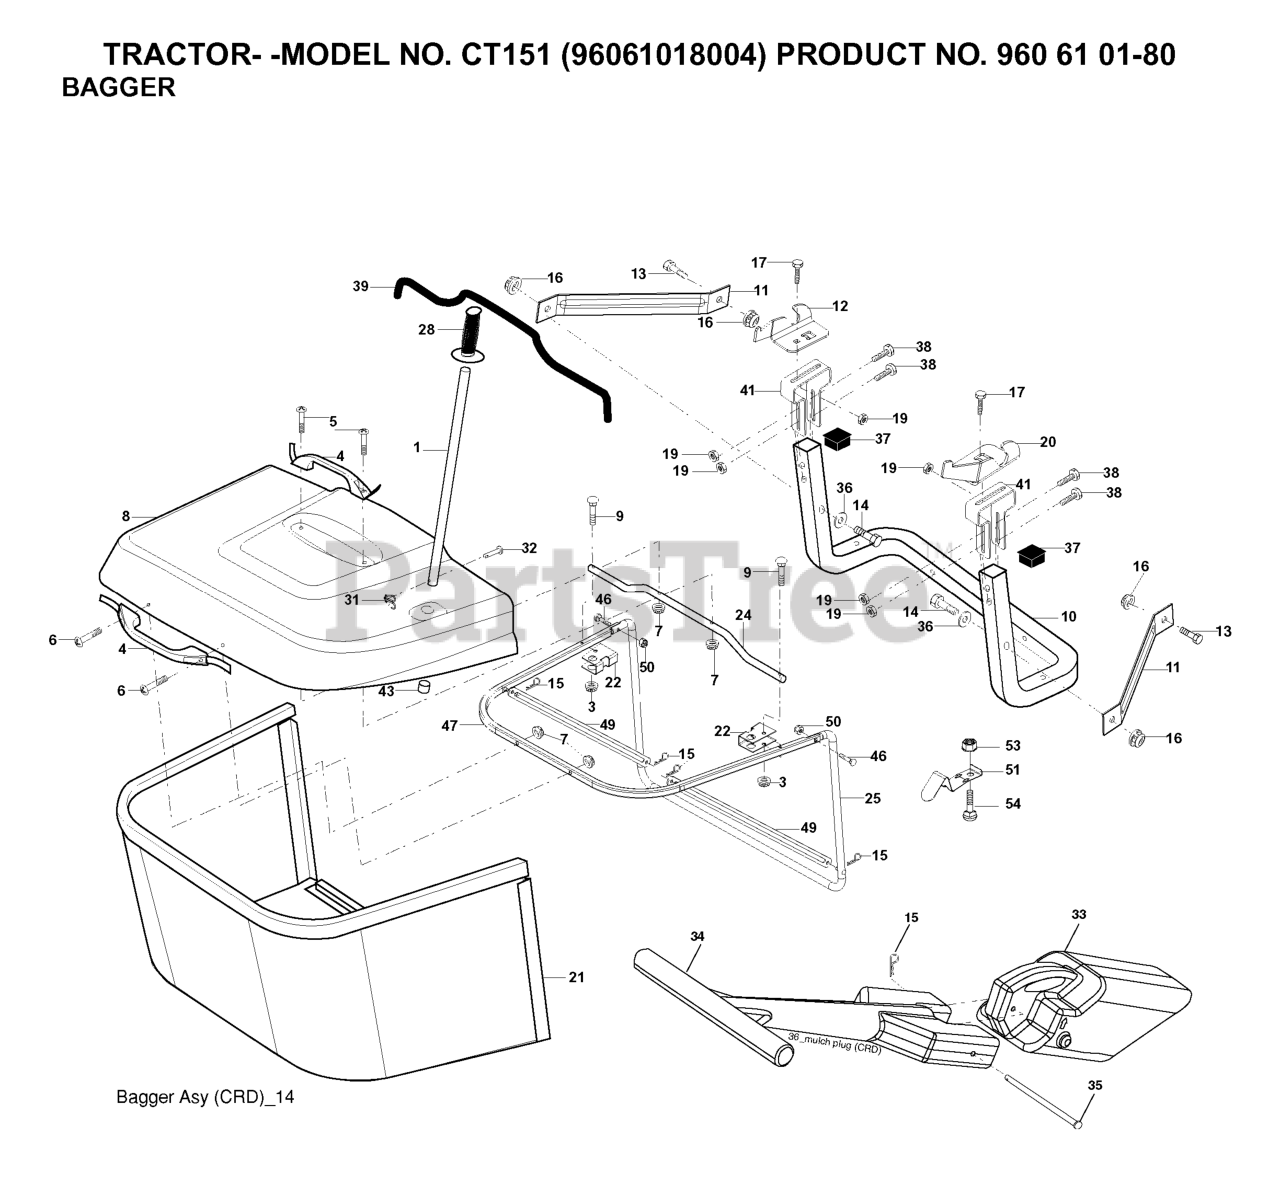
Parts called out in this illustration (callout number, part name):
1	TUBE HANDLE
3	NUT T
4	HANDLE.BAGGER.W/LVRS.BLK.CRD
5	SCREW.PAN.HEAD
6	REPL BY 532 75 00-29
8	COVER.PNT.BGR.CRD.WSLOTS.MS668
9	Bolt Carriage 1/4-20 x 2.25d x Gr.5
10	TUBE
11	BRACKET.SUPPORT.UPPER.BAG.CRD
12	BRKT PIVOT
14	BOLT-HEX EAK
15	RETAINER-SPRNG RB
16	NUT LOCK FLG 3/8-16 UNC
17	RP BOLT 5/16-18 X3/4 ZN/YEL GR
19	NUT LOCK HEX FLANGE 5/16-18
20	BRKT.PIVOT.RH.CRD
21	BAGGER.ASM.CRD.2007
22	BRKT.SIDE.BAG.CRD
24	TUBE.PIVOT.BAG.CRD.BLACK
25	PIPE
28	GRIP.HANDLE.BLACK
31	RETAINER CLIP
32	RIVET,DRILLED
33	PLUG.MULCHER.92 CRD
34	HANDLE.MULCHER.92.CRD (2 2)
36	WASHER
37	Plug Support Bagger CRD
38	BOLT.5/16-18X2.5
39	SEAL.TRIM.37'
41	BRKT.VERT.ADJ.BAGGER.CRD
43	PLUG, TUBING END
46	BOLT.CARRIAGE.5/16-18
47	PIPE
49	ROD
50	NUT.71038.31-18.HEX.NYLOCK
51	LATCH
53	NUT
54	BOLT
